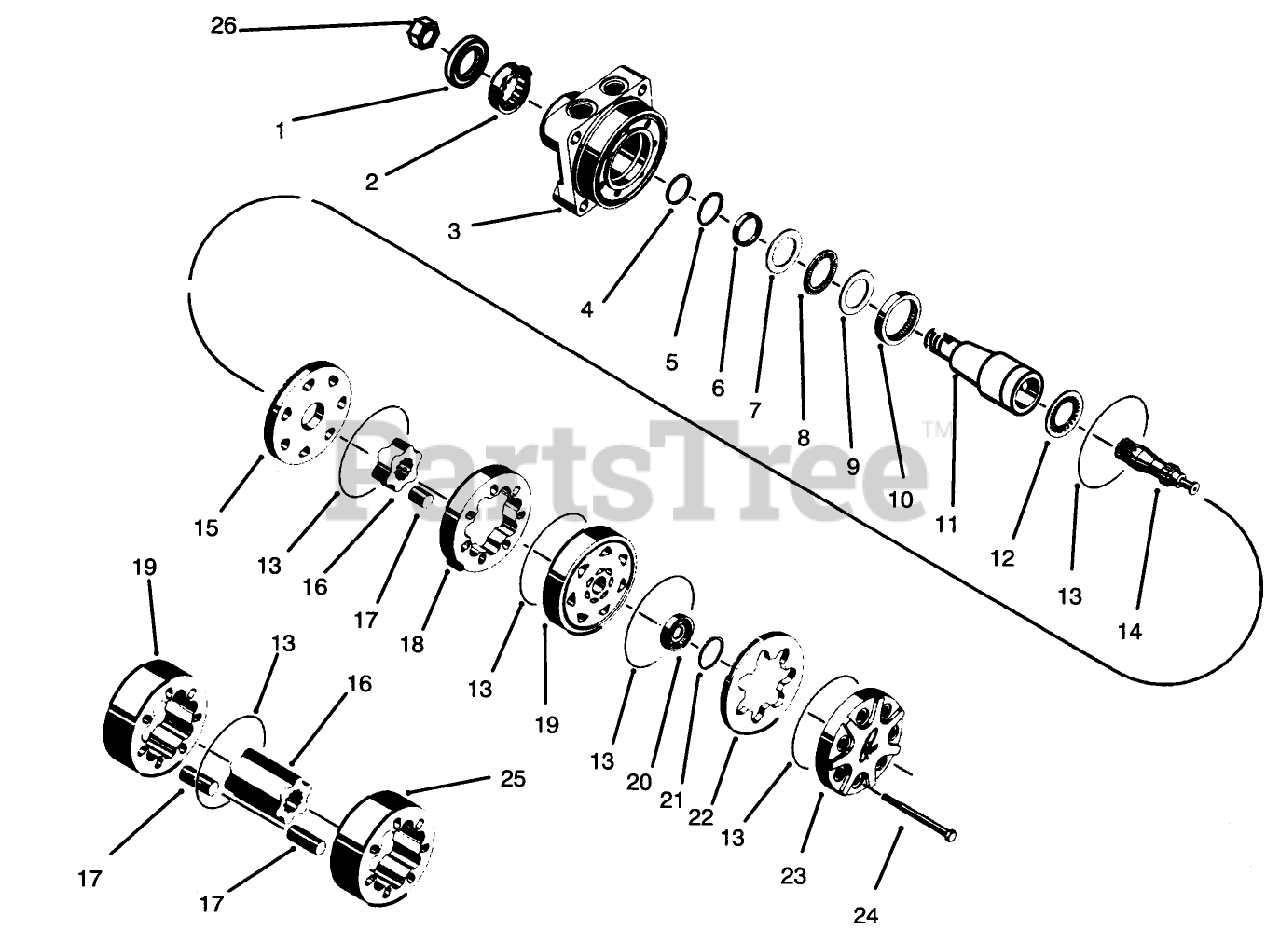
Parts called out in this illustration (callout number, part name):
1	Seal ASM
2	Loose Parts Package
3	Loose Parts Package
4	Washer-Back Up
5	Washer-Back Up
6	Seal ASM
7	Loose Parts Package
8	Loose Parts Package
9	Loose Parts Package
10	Bearing-Inner
11	Coupling-Shaft
12	Loose Parts Package
13	Loose Parts Package
14	Link-Drive
15	Plate Wear
16	Loose Parts Package
17	Loose Parts Package
18	Loose Parts Package
19	Loose Parts Package
20	Loose Parts Package
21	Loose Parts Package
22	Commutator-Ring
23	Cover-End
24	Special
25	Stator Half
26	NUT-MOTOR, WHEEL
